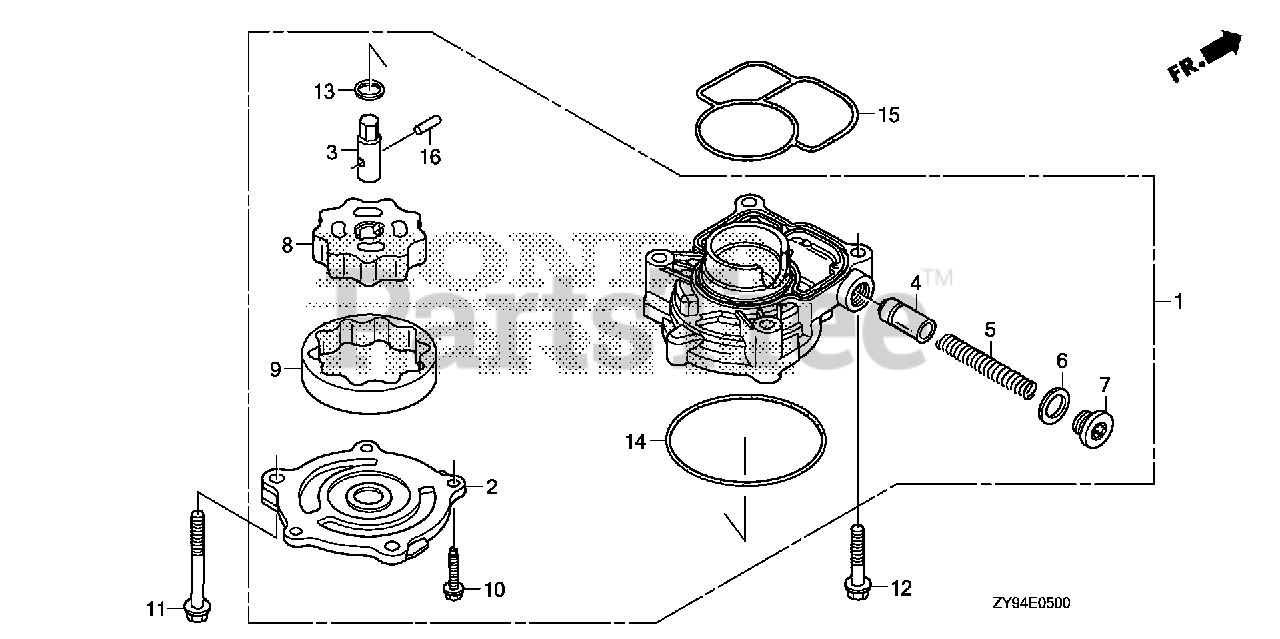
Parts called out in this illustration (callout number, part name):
1	PUMP ASSY., OIL
2	COVER, OIL PUMP
3	SHAFT, OIL PUMP
4	VALVE, RELIEF
5	SPRING, RELIEF VALVE
6	WASHER, SEALING (18MM)
7	BOLT, SEALING (18MM)
8	ROTOR (INNER)
9	ROTOR (OUTER)
10	BOLT, FLANGE (6X18) (CT200)
11	BOLT, FLANGE (8X60)
12	BOLT, FLANGE (8X40)
13	WASHER, THRUST (12MM)
14	O-RING, PUMP COVER
15	O-RING, OIL PUMP
16	ROLLER (5X17.8)
